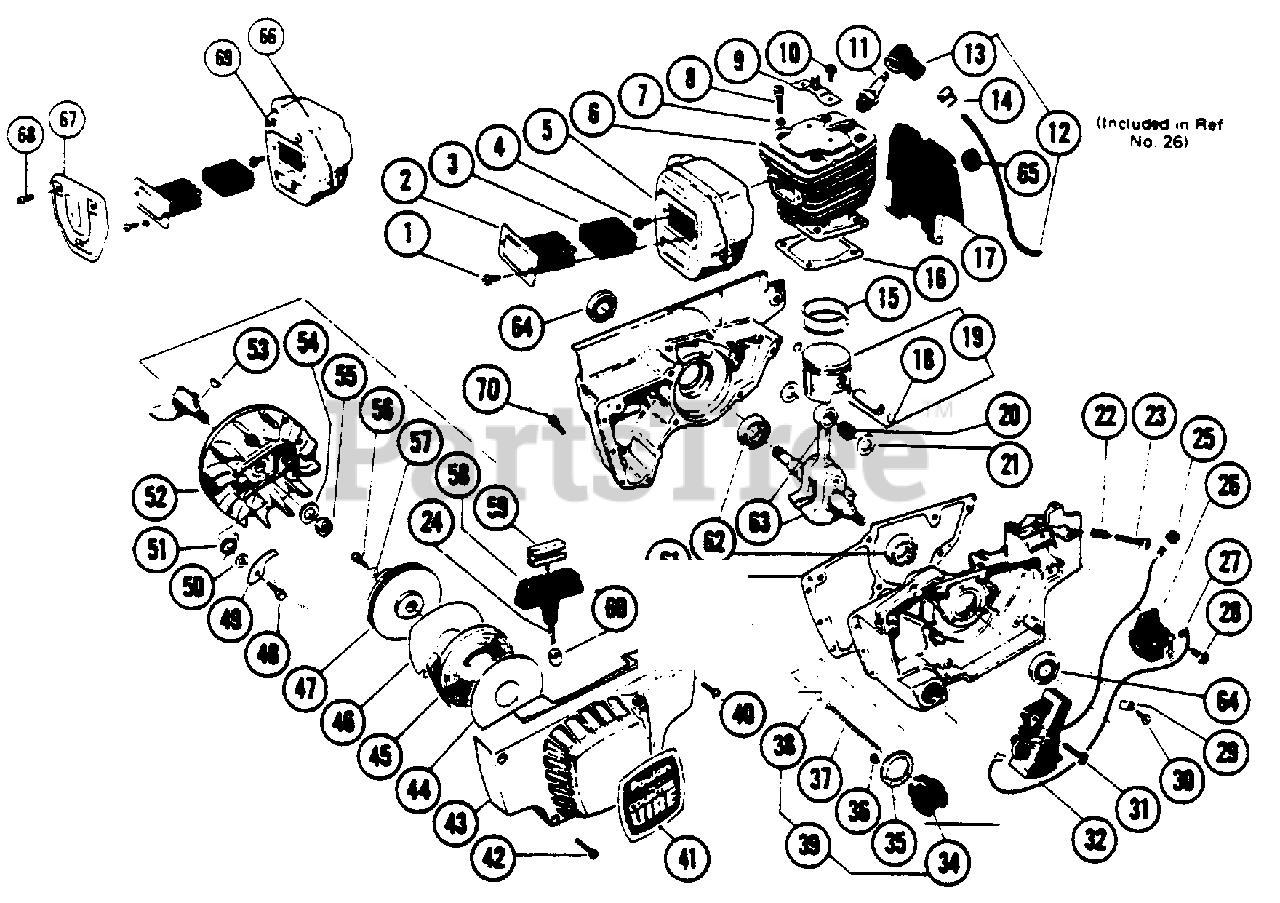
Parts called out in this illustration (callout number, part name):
1	Screws - 10-32 x 1/2
2	Diffuser - Muffler
3	Screen - Spark Arrestor
4	Screw - Muffler (12-24 x 5/8)
5	Body - Muffler
6	Cylinder - 4200
6	Cylinder - 5200
7	Lockwasher - Cylinder
8	Screw - 1/4-20 x 1 Socket Head
9	Bracket - Cylinder Cover
10	Screw - Cylinder Cover Bracket
11	Spark Plug 4200 & 5200
12	Wire Ass'y. - Ignition (includes 13 & 14)
13	Boot - Spark Plug
14	Connector - Spark Plug
15	Piston Ring 4200
15	Piston Ring 5200
16	Gasket - Cylinder Included in Gasket Kit 69025
17	Baffle - Air
18	Retainer - Piston Pin
19	Piston Ass'y. 4200 (includes 18)
19	Piston Ass'y. 5200 (includes 18)
20	Bearing - Piston Pin
21	Washer - Thrust
22	Spring - Idle Speed Screw
23	Screw - Idle Speed
24	Rope - Starter
25	Grommet - Lead Wire (included in 32) Included in Gasket Kit 69025
26	Transformer Ass'y. (includes 12)
27	Lead Wire - Module to Transformer (included in 32)
28	Screw - 10 24 x 3/4
29	Clamp - Lead Wire
30	Screw - 8-32 x 5/16 Tapping
31	Screw - 10-24 x 7/8
32	Module - Ignition (includes 27 & 28)
35	Gasket - Oil Cap Included in Gasket Kit 69025
36	Screw - 8-32 x 3/8 5200 Only
37	Chain - Oil Cap 5200 Only
38	Retainer - Oil Cap Chain 5200 Only
39	Oil Cap Ass'y. 5200 Only (includes 34, 35, 36, 37 & 38)
40	Screw - 10-24 x 3/4 Oval Head
41	Decal - Fan Housing 4200
41	Decal - Fan Housing 5200
42	Screw - 10-24 x 1 3/4 Oval Head
43	Fan Housing Ass'y. (includes 60)
44	Disc - Starter (Under Spring)
45	Spring - Starter Rewind
46	Disc - Starter (Over Spring)
47	Pulley - Starter
48	Stud - Starter Dog
49	Dog - Starter
50	Washer - Starter Dog
51	Spring - Starter Dog
52	Flywheel
53	Key - Flywheel
54	Washer - 3/8
55	Nut - Flywheel Mounting
56	Screw - 1/4-20 x 1/2 Socket Head
57	Washer - Starter Pulley
58	Handle - Starter Rope
59	Anchor - Rope
60	Bushing - Rope Grommet (included in 43)
61	Gasket - Crankcase Included in Gasket Kit 69025
62	Bearing - Crankshaft
63	Crankshaft & Connecting Rod
64	Seal - Crankshaft
65	Grommet-High Tension Lead Included in Gasket Kit 69025
66	Hexfastener & Muffler Ass'y. (opt.)
67	Heat Shield (opt.)
68	Hex Socket Cap Screw 1/4-20 x 5/8 (opt.)
69	Washer-Conical (opt.)
70	Screws #8 x 1/2 Socket Head
